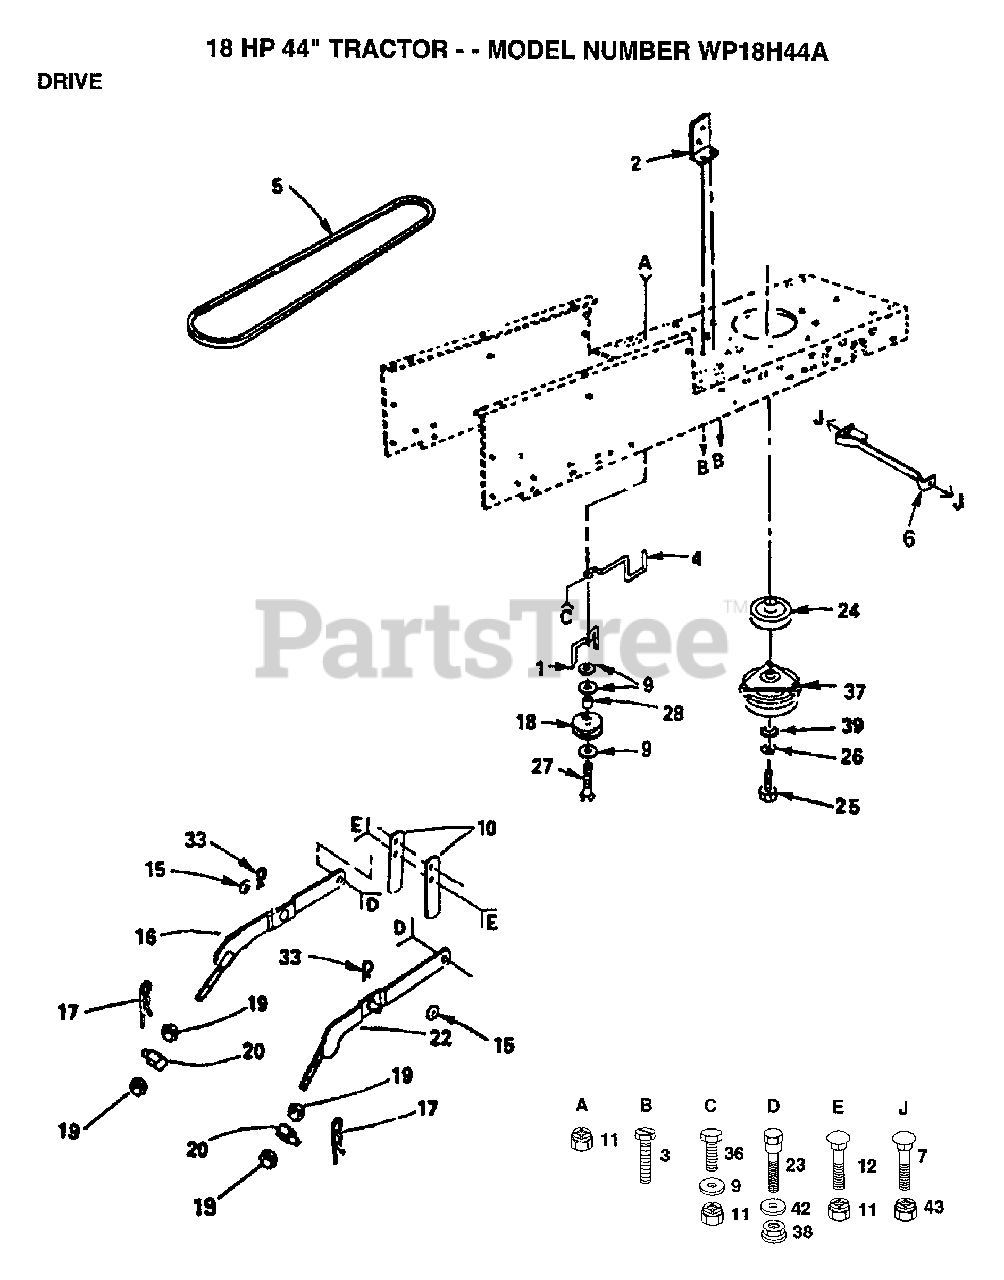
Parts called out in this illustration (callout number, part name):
1	BELT KEEPER LT
2	BRACKET LT
3	SCREW
4	KEEPER.BELT.ENG.L
7	BOLT
9	WASHER
10	UPSTOP
16	LH SUSP ARM ASM
17	SPRING H
18	PULLEY.IDLER.FLAT
19	NUT
22	RH SUSP ARM ASM
23	"BOLT, SHOULDER LT"
26	LOCKWASHER
27	BOLT
28	SPACER T
33	SPRING.RETAINER
36	BOLT
38	NUT SPECIAL T
39	WASHER
42	WASHER T
